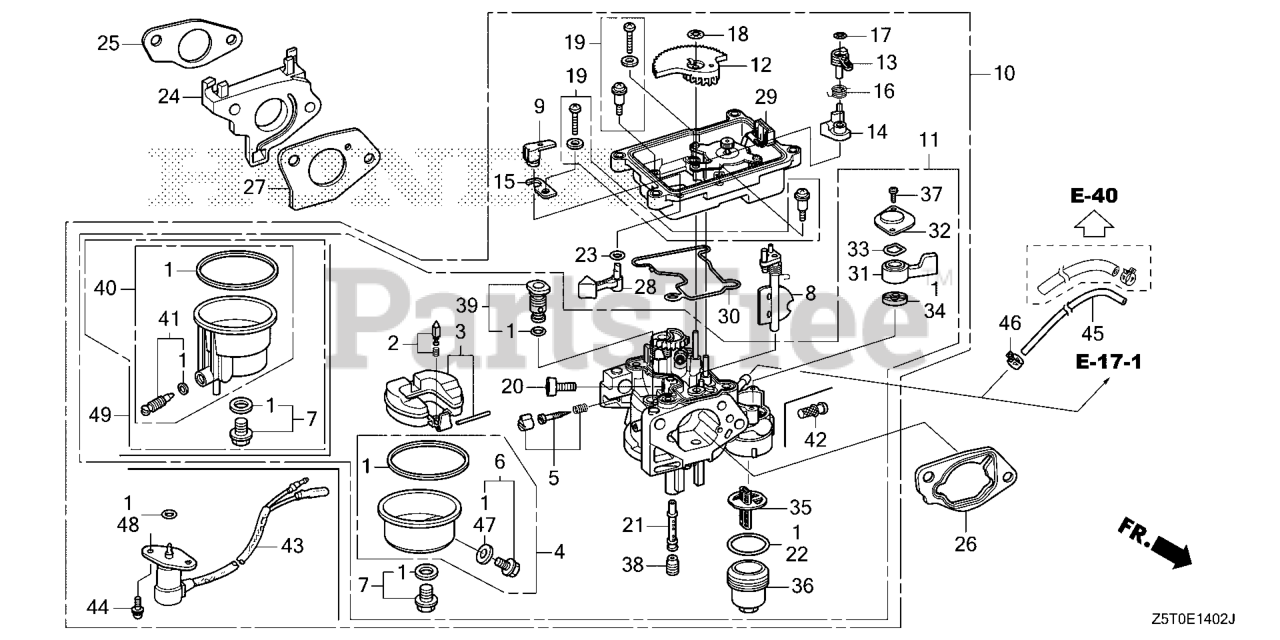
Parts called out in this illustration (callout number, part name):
1	GASKET SET (INCLUDE 16173-001-004) (INCLUDES 16173-001-004)
2	VALVE SET, FLOAT
3	FLOAT SET (CARBURETOR NO.)
4	CHAMBER SET, FLOAT
5	SCREW SET (CARBURETOR NO.)
6	SCREW SET, DRAIN
7	SCREW SET (CARBURETOR NO.)
9	ARM, MANUAL START
10	CARBURETOR ASSY. (BEC2A A)
11	CARBURETOR SET
12	GEAR, MIDDLE
13	ARM, CHOKE
14	LEVER, CHOKE CONTROL
16	SPRING, TORSION COIL
17	CLIP, SPECIAL
18	CLIP, SPECIAL
20	SCREW, STOP
21	NOZZLE, MAIN
22	GASKET, FUEL STRAINER CUP
23	O-RING (CARBURETOR NO.)
24	INSULATOR, CARBURETOR
25	GASKET, CARBURETOR INSULATOR
26	SPACER, CARBURETOR
27	GASKET, CARBURETOR
28	LEVER, MANUAL START
29	CASE, MOTOR
31	LEVER, VALVE
32	PLATE, LEVER SETTING (CARBURETOR NO.)
33	SPRING, PETCOCK LEVER (CARBURETOR NO.)
34	GASKET, VALVE
35	FILTER, CUP (CARBURETOR NO.)
36	CUP, FUEL STRAINER
37	SCREW, PAN (3X6)
38	JET, MAIN (#102) (ADVENTURE GREEN) (CARBURETOR NO.)
38	JET, MAIN (#105) Use from Engine SN BE87H A.
38	JET, MAIN (#108) (CARBURETOR NO.)
39	JET SET, PILOT (#40) (ADVENTURE GREEN) (CARBURETOR NO.)
47	WASHER, PLAIN (6.2X10.7 DRAIN) (CARBURETOR NO.)
